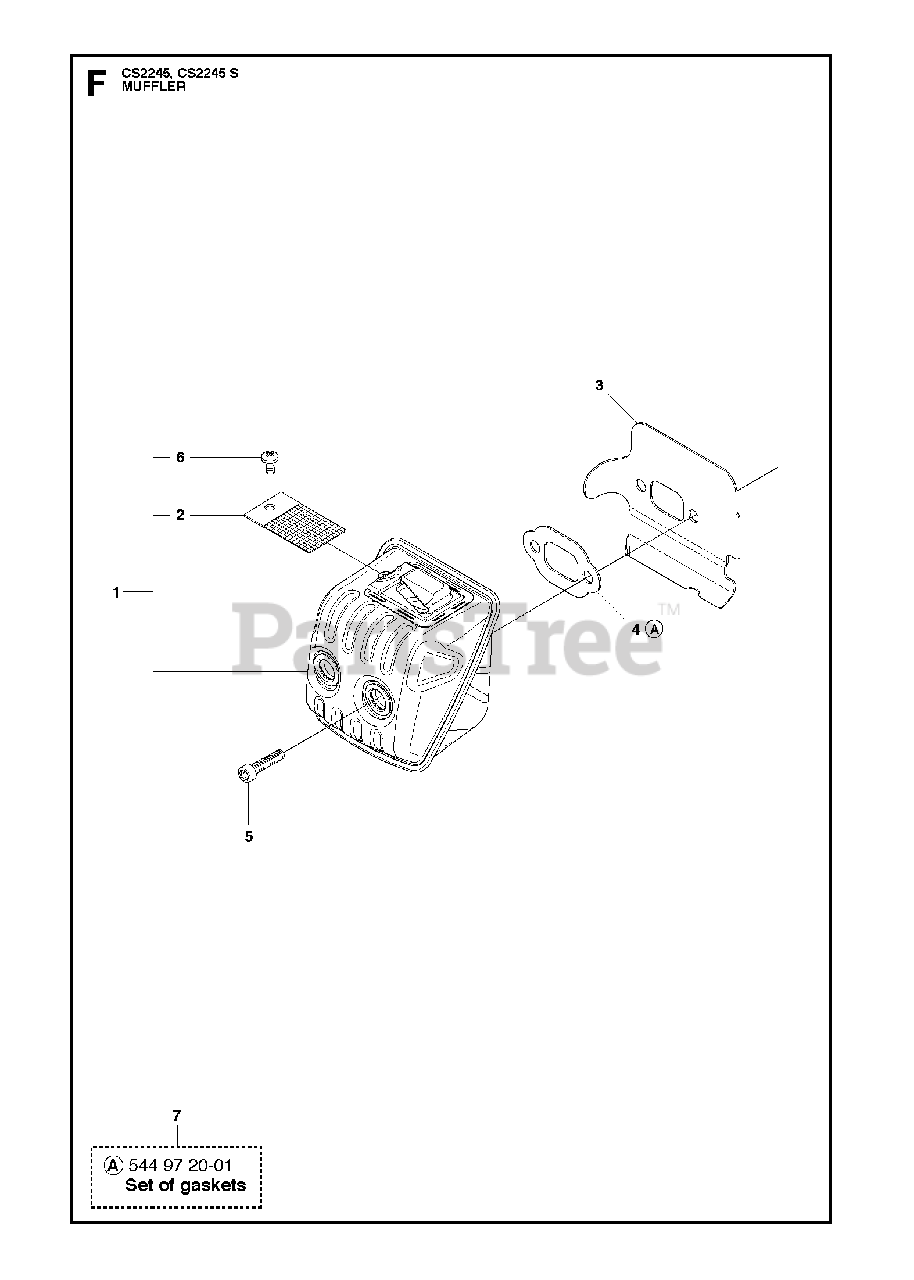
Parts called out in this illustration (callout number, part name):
1	MUFFLER ASSY
2	RP SCREEN
3	HEAT DEFLECTOR
4	GASKET
5	SCREW MC6S 6X16
6	SCREW
7	GASKET KIT
